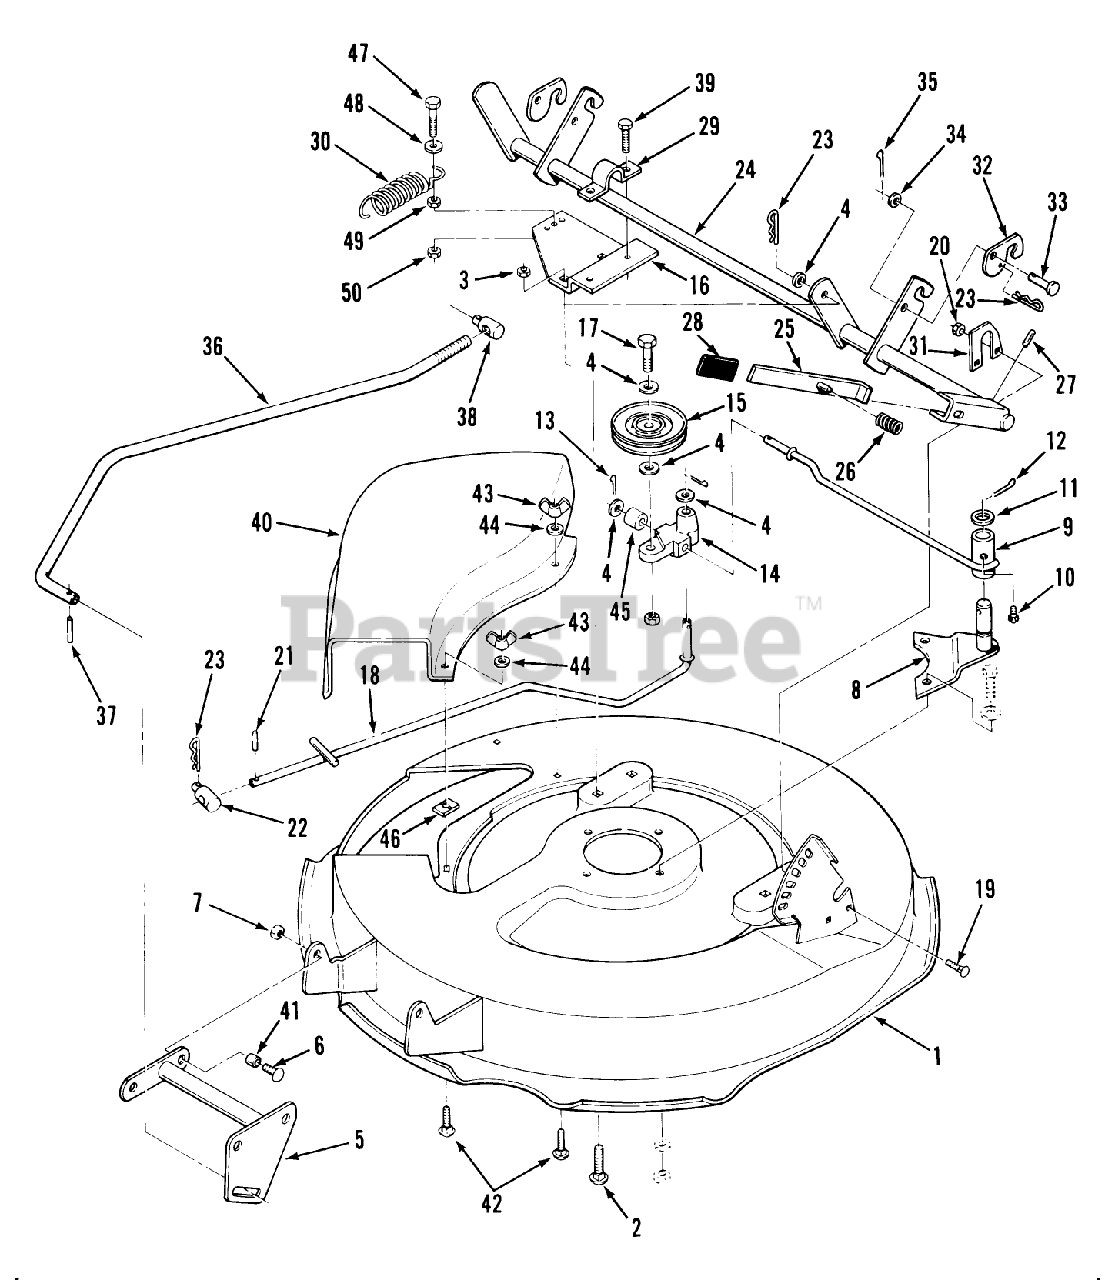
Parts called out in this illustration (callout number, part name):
5	ASM-FRONT LIFT *R
11	WASHER
14	BLOCK IDLER
15	PULLEY-IDLER V
22	TRUNNION-LIFT
23	Hairpin Cotter
24	ASSY-HEIGHT ADJ S *R
25	LEVER ASSY
26	SPRING-COMPRESSION
27	PIN-SPIROL
29	CLAMP
30	SPRING-CLUTCH
36	ASS'Y-HEIGHT ADJ *R
37	SPIROL PIN
38	STUD-TRUNION
39	Bolt
41	SPACER
44	WASHER
45	SPACER
46	SPEED NUT
48	WASHER 5/16 SAE
49	Nut 5/8-18
